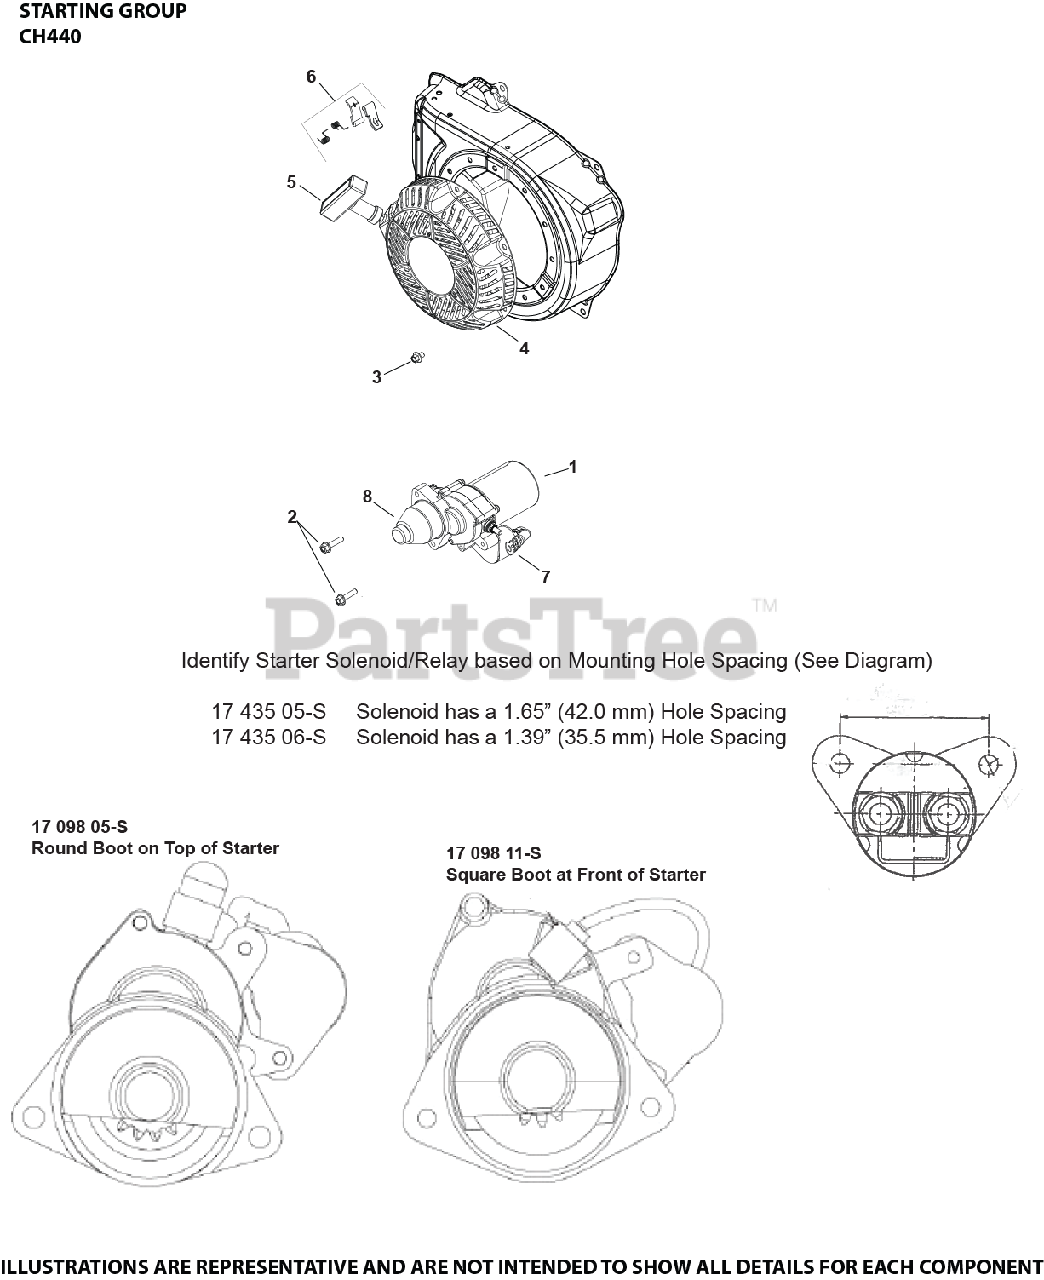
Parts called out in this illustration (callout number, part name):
1	ELECTRIC STARTER-BENDIX DRIVE
3	SCREW, M6 X 8 HEX FLANGE HEAD (CKY)
4	RETRACTABLE STARTER ASSEMBLY
5	KIT, HANDLE
6	KIT, PAWL REPAIR
8	KIT, STARTER DRIVE
